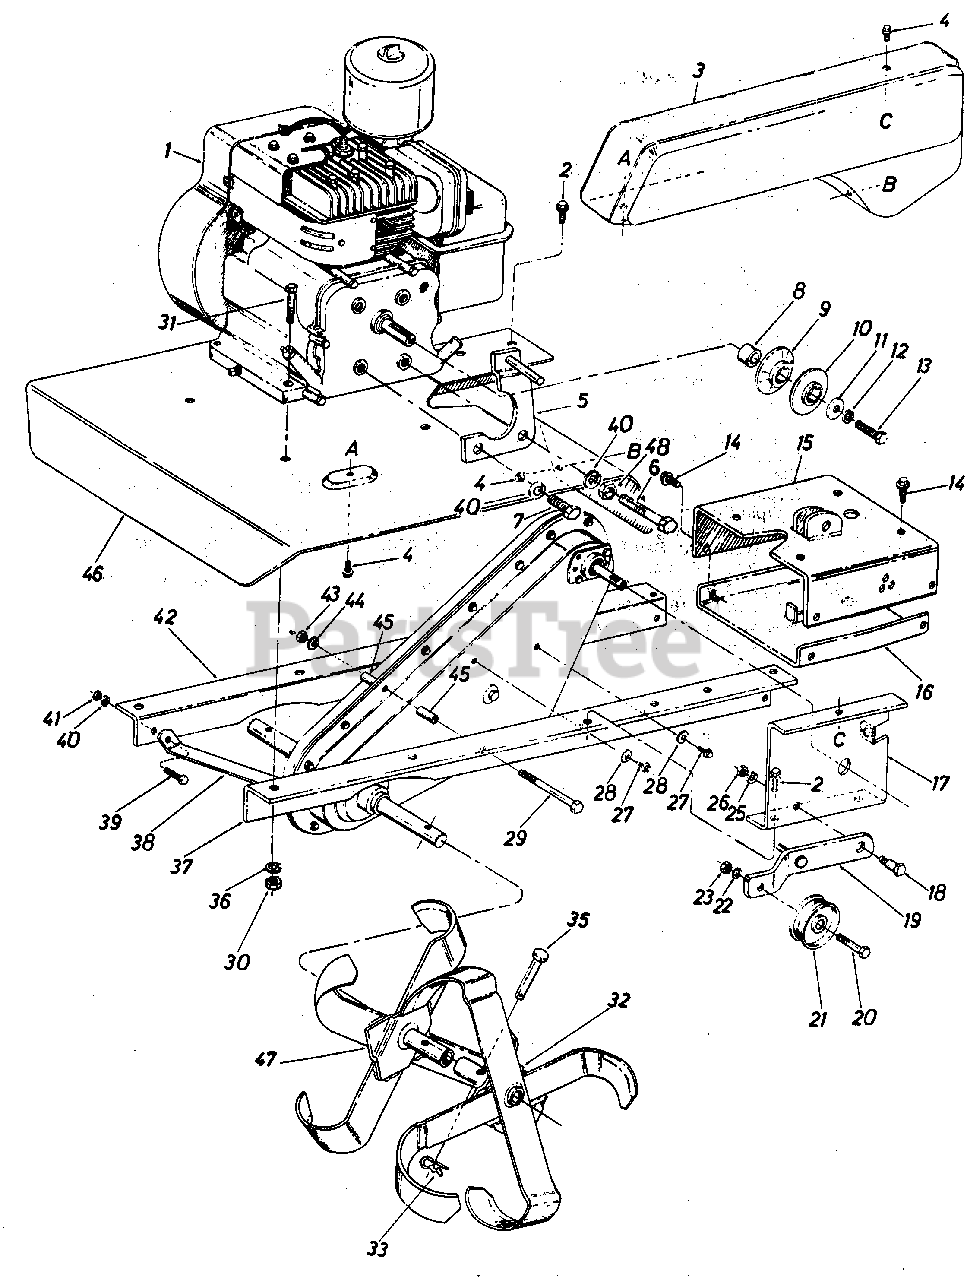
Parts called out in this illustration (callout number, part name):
1	Engine
2	Hex Wash. Hd. Self-Tap Scr. 5/16-24 x .50" Lg.
3	Belt Cover
4	Hex Wash. Hd. Self-Tap Scr. 1/4-20 x .50" Lg.
5	Belt Keeper Brkt. Ass'y.
6	Hex Bolt 5/16-24 x 2.25" Lg. (Gr. 5)
7	Hex Bolt 5/16-24 x .62" Lg. (Gr. 5)
8	Spacer
9	Pulley Half
10	Pulley Half
11	Fl-Wash. 3/8" I.D. x 1.25" O.D. x .100
12	L-Wash. 3/8" I.D.
13	Hex Scr. 3/8-24 x 1.00" Lg.
14	Hex Wash. Hd. Self-Tap Scr. 3/8-24 x 7/8" Lg.
15	Handle Mounting Brkt. Ass'y.
16	U-Channel Brkt. Ass'y.
17	Idler Mounting Brkt.
18	Shld. Bolt
19	Idler Brkt. Ass'y.
20	Hex Scr. 3/8-16 x 1.50" Lg.
21	Idler Pulley
22	L-Wash. 3/8" I.D.
23	Hex Nut 3/8-16 Thd.
25	L-Wash. 3/8" I.D.
26	Hex Nut 3/8-16 Thd.
27	Hex Wash. Hd. Self-Tap Scr. 1/4-20 x .50" Lg.
28	Belleville Wash. .26 I.D. x .75 O.D. x .060
29	Hex Scr. 5/16-18 x 3.0" Lg.
30	Hex Nut 5/16-18 Thd.
31	Hex Bolt 5/16-18 x 1.50" Lg.
32	See Tine Chart
35	Clevis Pin
36	L-Wash. 5/16" I.D.
37	Frame Rail L.H.
38	Front Brace Brkt.
39	Hex Scr. 5/16-18 x .75" Lg.
40	L-Wash. 5/16" I.D.
41	Hex Cent. L-Nut 5/16-18 Thd.
42	Frame Rail R.H.
43	Hex Cent. L-Nut 5/16-18 Thd.
44	L-Wash. 5/16" I.D.
45	Spacer
46	Tine Shield
47	See Tine Chart
